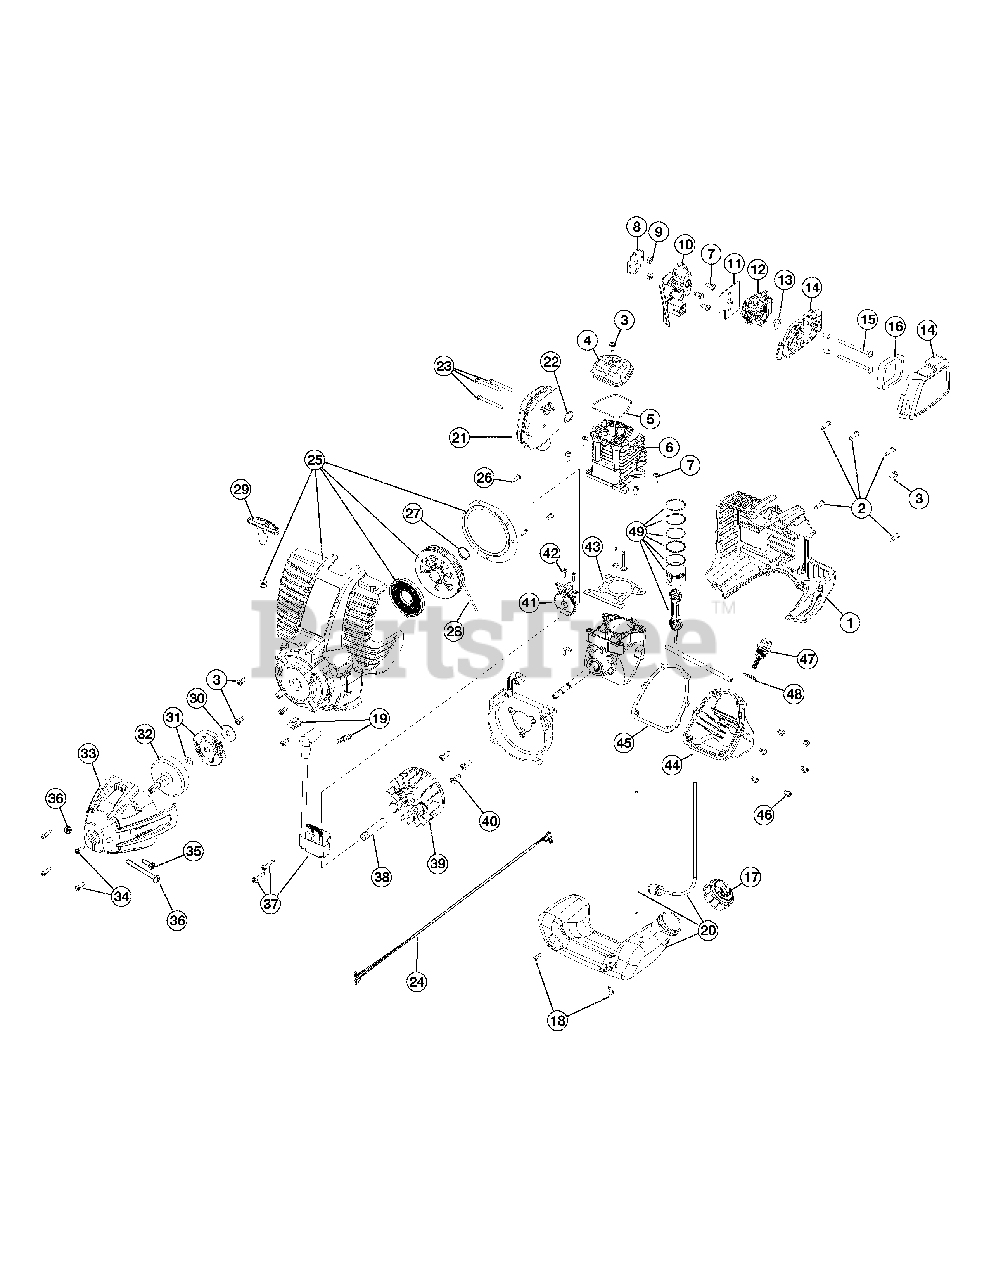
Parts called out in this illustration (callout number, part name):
1	Engine Cover
3	Screw
4	Valve Cover
5	Valve Cover Gasket
6	Cylinder Assembly
7	Cylinder Screw
8	Insulator Gasket
9	Nut
10	Insulator
11	Carburetor Gasket
12	Carburetor w/Primer
13	Carburetor O-Ring
14	Air Filter Cover Assembly
15	Air Filter Mounting Screw
16	Air Filter
17	Fuel Cap
19	Clip Nut
20	Fuel Tank Assembly
21	Muffler Assembly
22	Muffler Gasket
23	Muffler Mounting Screw
24	Lead Wire
25	Starter Housing Assembly
26	Plate Screw
27	Push Nut
29	Pull Handle
30	Washer
31	Clutch Assembly
32	Clutch Drum
33	Clutch Cover Assembly
34	Cover Screw
35	Anti-Rotation Screw
36	Clamping Screw Assembly
37	Ignition Module Assembly
38	Spacer
39	Flywheel Shroud
41	Cam Bracket Assembly
42	Cam Bracket Screw
43	Cylinder Gasket Oil Pan
44	Oil Pan
46	Oil Pan Screw
47	Dipstick Assembly
49	Piston Assembly
